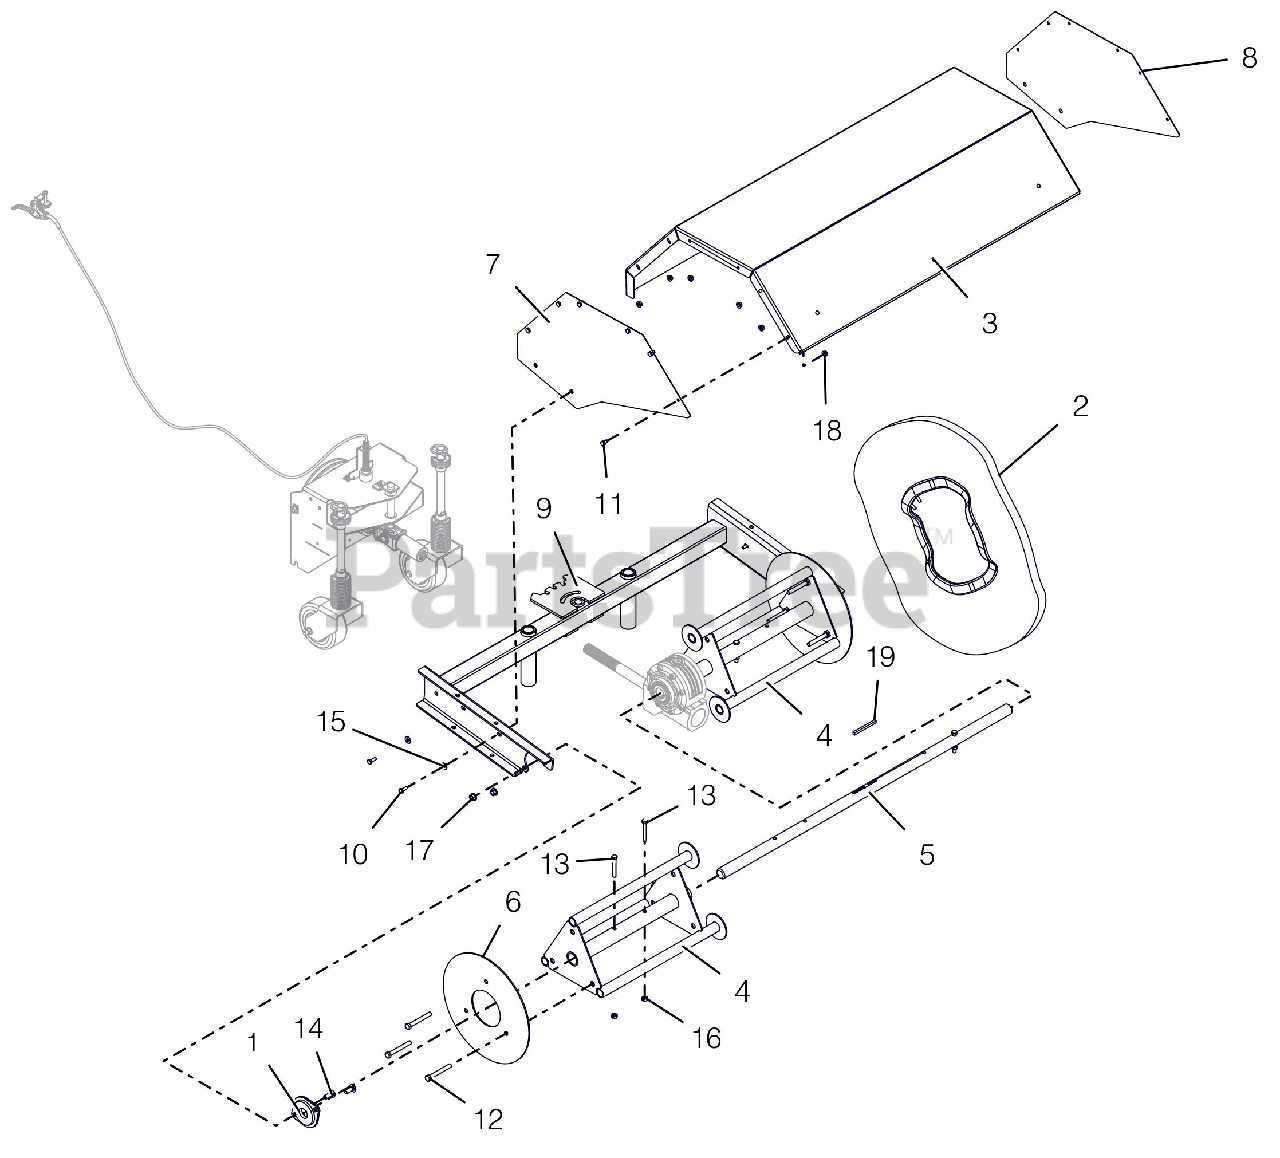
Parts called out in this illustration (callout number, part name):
1	BEARING,2 BOLT FLANGE 1-1/8 ID
2	KIT, BRISTLE - SET OF 18
3	COVER, TOP - 36" BRUSH W/DECAL
4	PB36 DRIVE CORE SERVICE KIT
5	CENTER, SHAFT
6	PLATE, END RETAINER
7	WLDT, SIDE COVER - RH
8	WLDT, SIDE COVER - LH
9	FRAME, POWER BROOM 36"
10	@BLT-HEX .25-20X.75 GR5 YWZC
11	@BLT-HEX .25-20X.50 GR5 YWZC
12	BLT-HEX .38-16X3.00 GR5 FTH YZ
13	@BLT-HEX .31-18X2.25 GR5 YWZC
14	@BLT-RDHDSQNK .38-16X1.00 G5YZ
15	@WSHR-FL-STL.312X.734X.065 YWZ
16	@NUT-LK-CTR .31-18 YWZC
17	@NUT-LK-TOP-FLG .38-16 YWZC
18	@NUT-LK-TOP-FLG .25-20 YWZC
19	KEY .25 X .25 X 3IN
